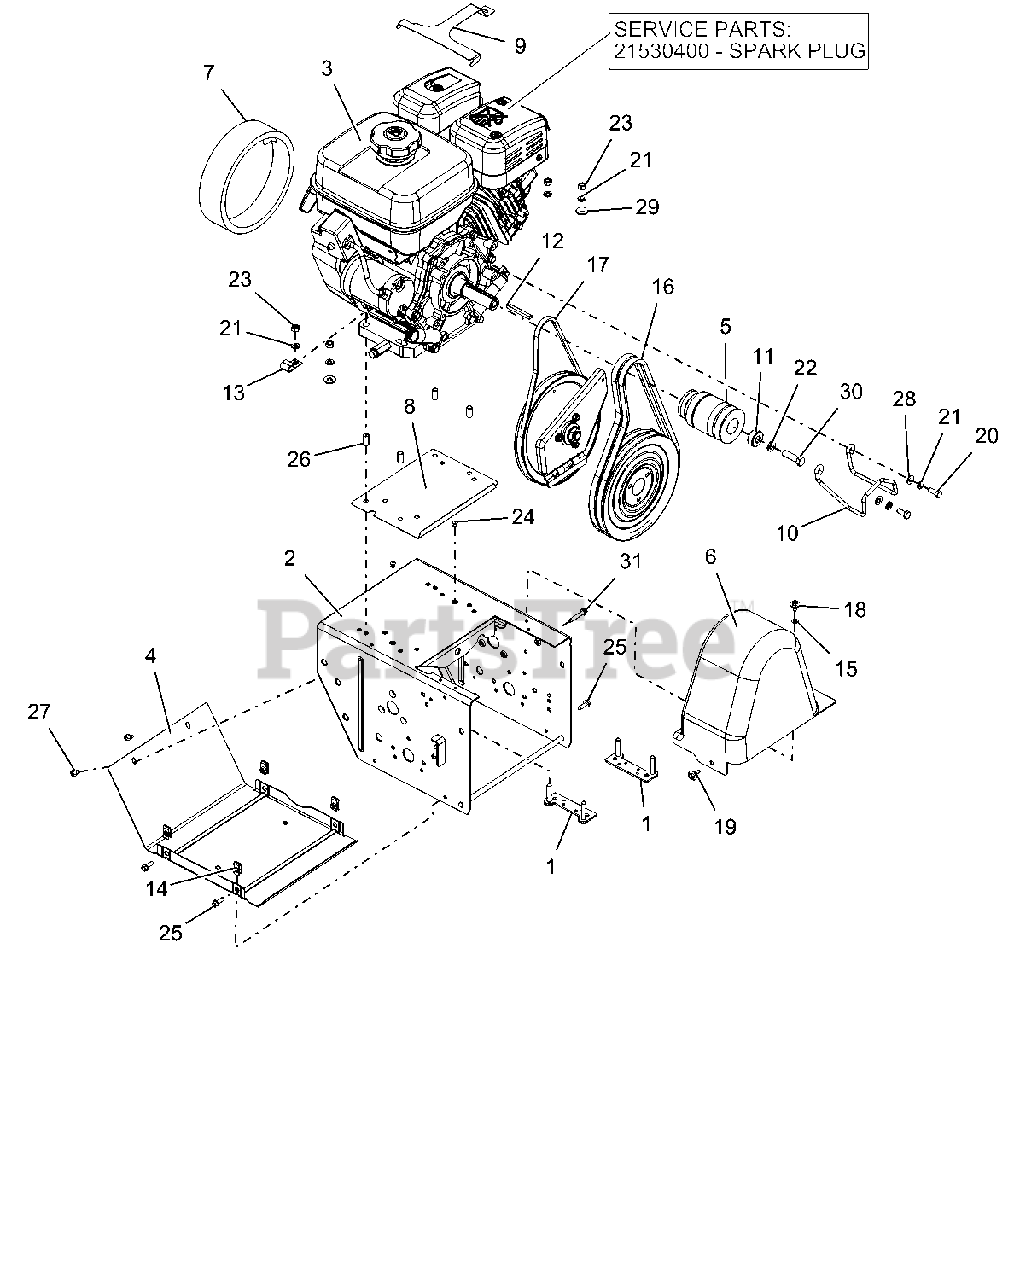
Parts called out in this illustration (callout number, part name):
1	STRAP, ENGINE BOLT-LARGE BRIGG
2	FRAME, MAIN - PRO SNOW
3	PLUG, SPARK - TEC. SNO-THRO
3	ENGINE,SUBARU EX27 AS 120V
4	COVER, BOTTOM
5	SHEAVE, SUBARU EX27
6	COVER, BELT-TALL PRO
7	FOAM COVER, RECOIL-SUBARU
8	BAFFLE, WATER-PRO SERIES
9	GUARD, SNOW-SUBARU
10	FINGER, BELT
11	BSHG-SPACER .47X1.25X.50
12	KEY .25X.25X2.25
13	J-CLAMP
14	NUT-RTNR .25-20X.56
15	NUT-PUSH .25X.50 O.D.
16	V-BELT, HA-RAW EDGE (SET)
17	V-BELT, 3L-RAW EDGE
18	SCR-TAP .25-20X.50 LGHWH TR YZ
19	SCR-TAP .25-20X.5 CAPTIVE
20	BLT-HEX .31-24X.75 YWZC GR5
21	WSHR-LK .312X.097 HVY YWZC
22	@WSHR-LK .44X.109 REG YWZC
23	@NUT-HEX .31-18 YWZC
24	RVT-POP .187 YZ
25	BLT-HEX .25-20X.75 HWH YZ GR5
26	BSHG-SLV .325X.400X.795
27	SCR-TAP .25-20X.50 HWH TR YWZ
28	@WSHR-FL-STL.344X.688X.065YWZC
29	@WSHR-FL-STL.38X.875X.083 YWZC
30	BLT-HEX .44-20X1.50 G5 YZ EP80
31	@SCR-TAP .25-20X1.50 HWH TR YZ
